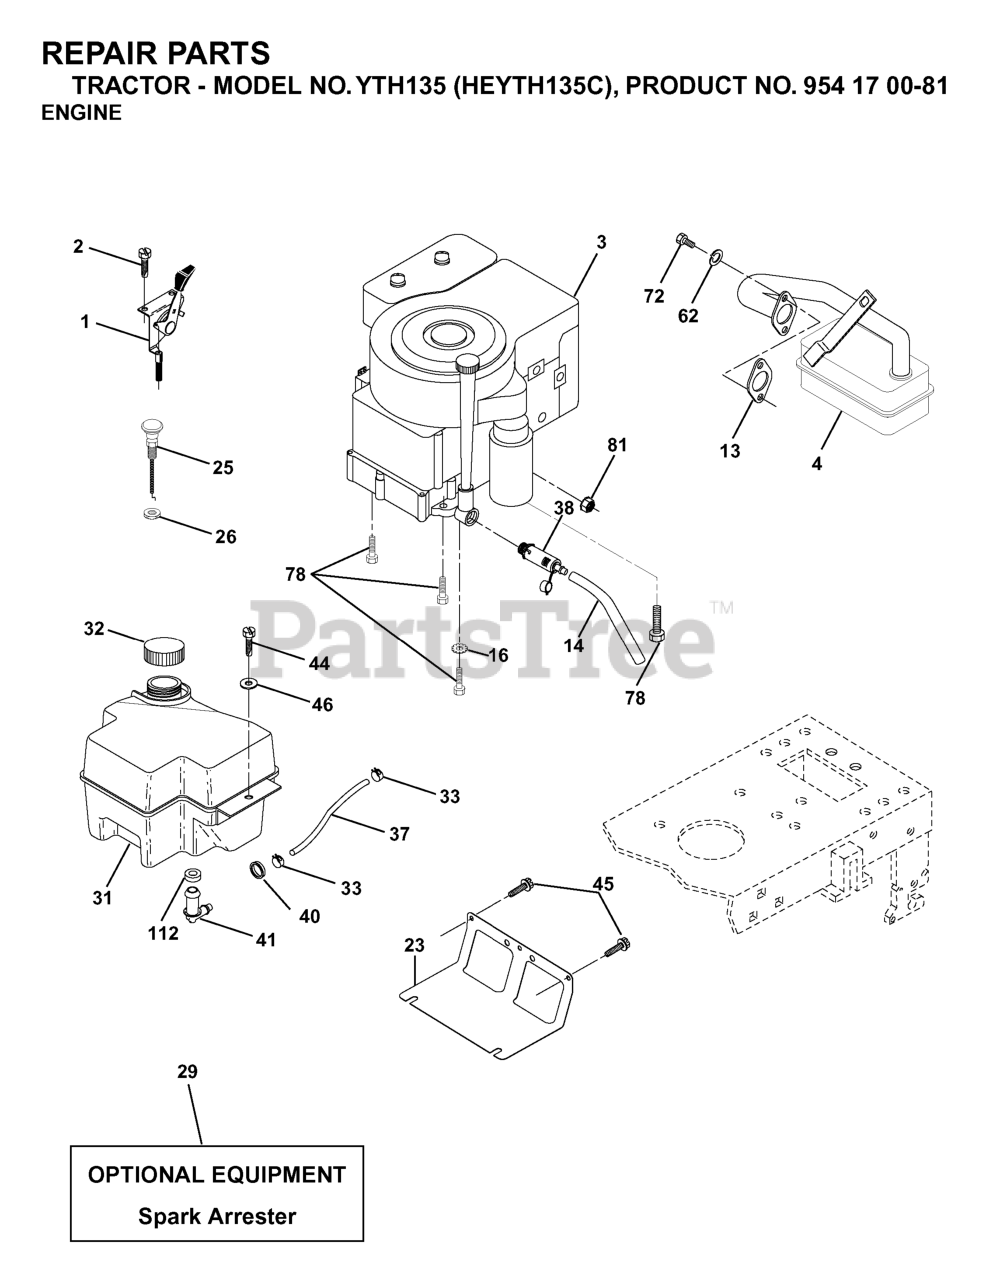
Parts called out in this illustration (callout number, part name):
1	CONTROL.THROTTLE/CHOKE.BLACK
2	SCREW
4	MUFFLER.LT.BRIGGS.14HP.IC/OHV
13	REPL BY 532 27 22-93
14	TUBE, DRAIN OIL ASM.
16	LOCKWASHER
23	SHIELD.BROWNING.DBR.GUARD
26	Nut Keps 3/8 - 24 UNF
29	KIT.SPARK ARRESTOR 794945 B&S
31	GAS TANK 2GAL
32	FUEL CAP
33	HOSE CLAMP
37	LINE.FUEL.20
38	PLUG DRAIN OIL EASY
40	BUSHING.SNAP.NYL.BLK.
41	STEM FUEL TANK
44	SCREW HEXWSHR 1/4-20X3/4
45	SCREW, 3/8-16X3/4
46	WASHER
62	WASHER.LOCK.HVY.HLCL.SPR.5/16
72	SCREW
78	SCREW.3/8-16
81	NUT
112	BUSHING OUTLET T
